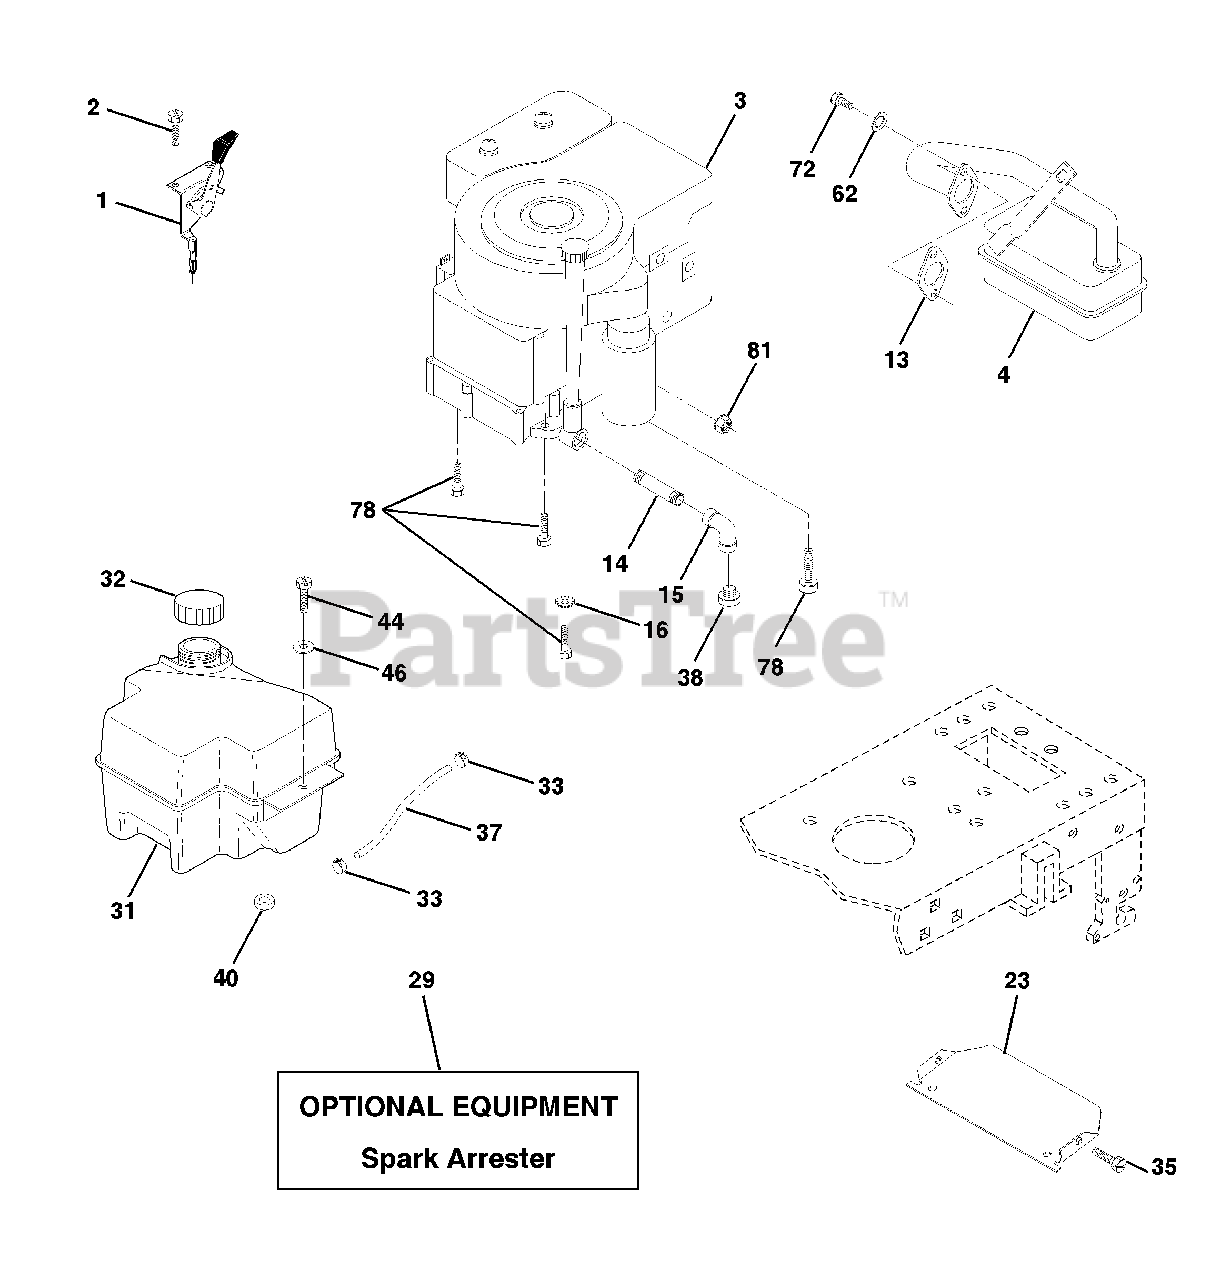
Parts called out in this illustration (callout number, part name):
1	Control Th/ch 23 5 LH Flag
2	Screw Hex Thd Cut 1/4-20x5/8 T
3	Engine
4	Muffler LT B&S 12/12.5/13HP
13	Gasket Eng 1 313 Id Tin Plated
14	Nipple Pipe 3/8 Npt X 3"
15	Elbow Std 90 Degree 3/8-18 Npt
16	Washer Lock Ext Tooth 3/8
23	Shield Heat
29	Kit Spark Arrestor (Flat Scrn)
31	Tank Fuel Front 2 00
32	Cap Asm Fuel W/sym Vented
33	Clamp Hose Black
35	Screw
37	Line Fuel 20"
38	Plug Oil Drain
40	Bushing Snap Nyl Blk Fuel Line
44	Screw Hexwsh Thdrol 1/4-20 x 3/4
46	Washer 9/32 X 7/8 X 16 Ga
62	Washer Lock Hvy Hlcl Spr 5/16
72	Screw Hexhd Cap 5/16-18 x 3/4
78	Screw Thdrol 3/8-16 x 1-1/4 TYTT
81	Nut Flange 1/4-20 Starter Nut
